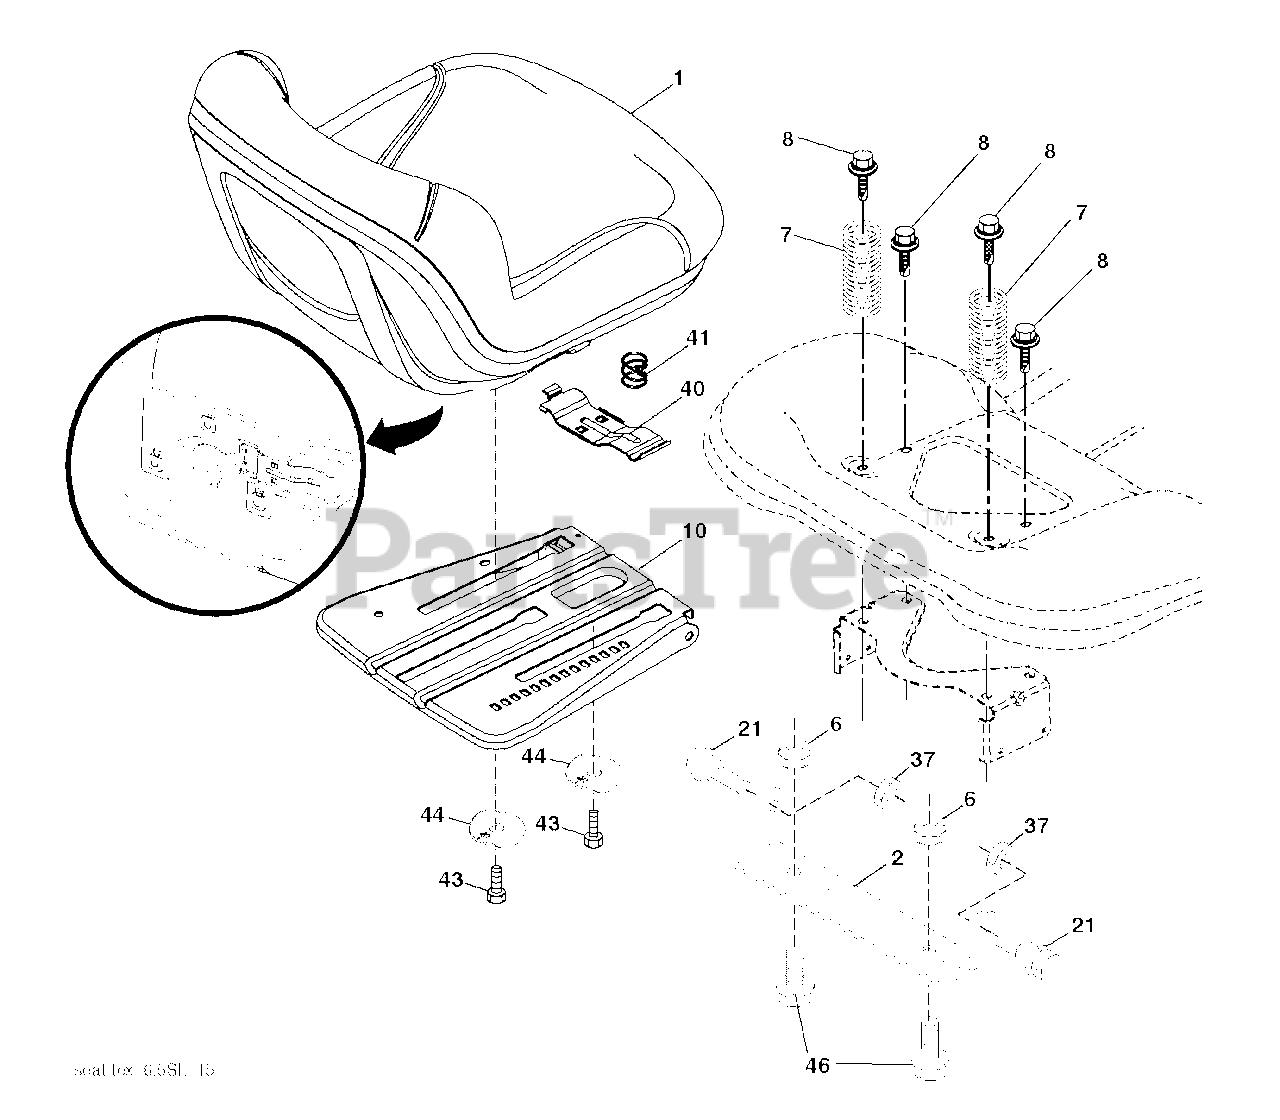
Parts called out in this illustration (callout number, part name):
1	SEAT.TH150.MS498.GRY.HUSQ.TEX
2	BRKT.PIVOT.FENDER
6	NUT
7	SPRING.COMPRESS.SEAT.
8	BOLT, 5/16-18 X 1 3/4
10	Seat Slide Plate, Pnt
21	BOLT.5/16-18X5/8.SHOULDER
37	NUT.71038.31-18.HEX.NYLOCK
40	HANDLE.SLIDE.SEAT.TEX.BLACK
41	SPRING.LATCH.SEAT.TEX
44	Winged Washer, 38Id 1
46	BOLT.3/8-16X1;1.25OD.WSHR.SEMS
